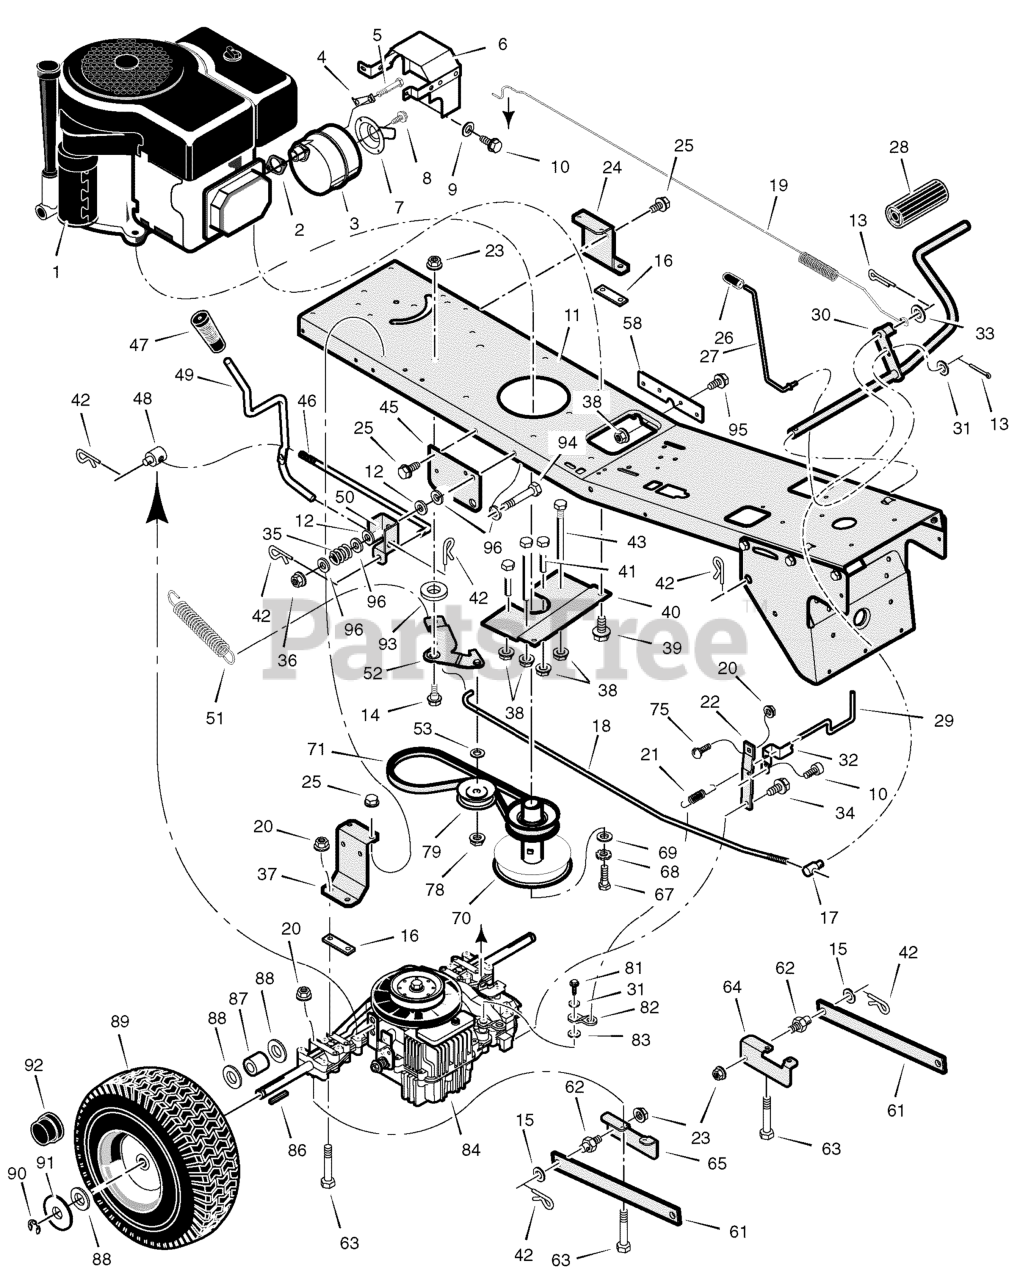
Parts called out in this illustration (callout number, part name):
1	Engine
2	Gasket, Muffler
3	Muffler
4	Lock, Muffler Screw
5	Bolt, Hex
6	Shield, Heat
7	Tube, Exhaust
9	Washer, Lock
10	Screw
12	Washer
13	Pin, Cotter
14	Bolt, Shoulder
15	Washer
16	Plate, Transaxle
17	Nut, Adjusting
18	Rod, Clutch Hydro
19	Spring, Brake
20	Nut
21	Spring, Roll Release
22	Bracket, Torque Strap
23	Nut
24	Bracket, Left Transaxle
25	Screw
27	Rod, Parking Brake
28	Pedal
29	Rod, Roll Release
30	Rod, Clutch/Brake
31	Washer
32	Bracket, Roll Release
33	Washer
34	Screw
35	Spring, Compression
37	Bracket, Right Transaxle
39	Screw
40	Plate, Belt Guide
41	Guide, Belt -Long
42	Pin, Hair
43	Guide, Belt -Short
45	Bracket, Lift Pivot
46	Rod, Shift Link
47	GRIP, Lift Lever
48	Nut, Adjusting
49	Lever, Shift
50	Bracket, Pivot
51	Spring - Variator Drive
52	Arm, Idler
53	Washer
58	Plate, Reinforcement
61	Arm, Rear
62	Pin, Threaded
63	Bolt, Hex
64	Bracket, Left Rear Hanger
65	Bracket, Right Rear Hanger
67	Bolt, Hex
68	Lockwasher
69	Washer
70	Pulley Stack
71	Belt, Drive
75	Bolt, Carriage
78	Locknut
79	Pulley, Idler
81	Cap Screw
82	Arm, Disconnect
83	Washer
84	Transaxle
86	Key, Square
87	SPACER, Rear Wheel
88	Washer
89	Wheel & Tire Assembly
90	E-Ring
91	Washer
92	Hub Cap
93	Washer
94	Bolt, Hex
95	Screw
96	Washer
